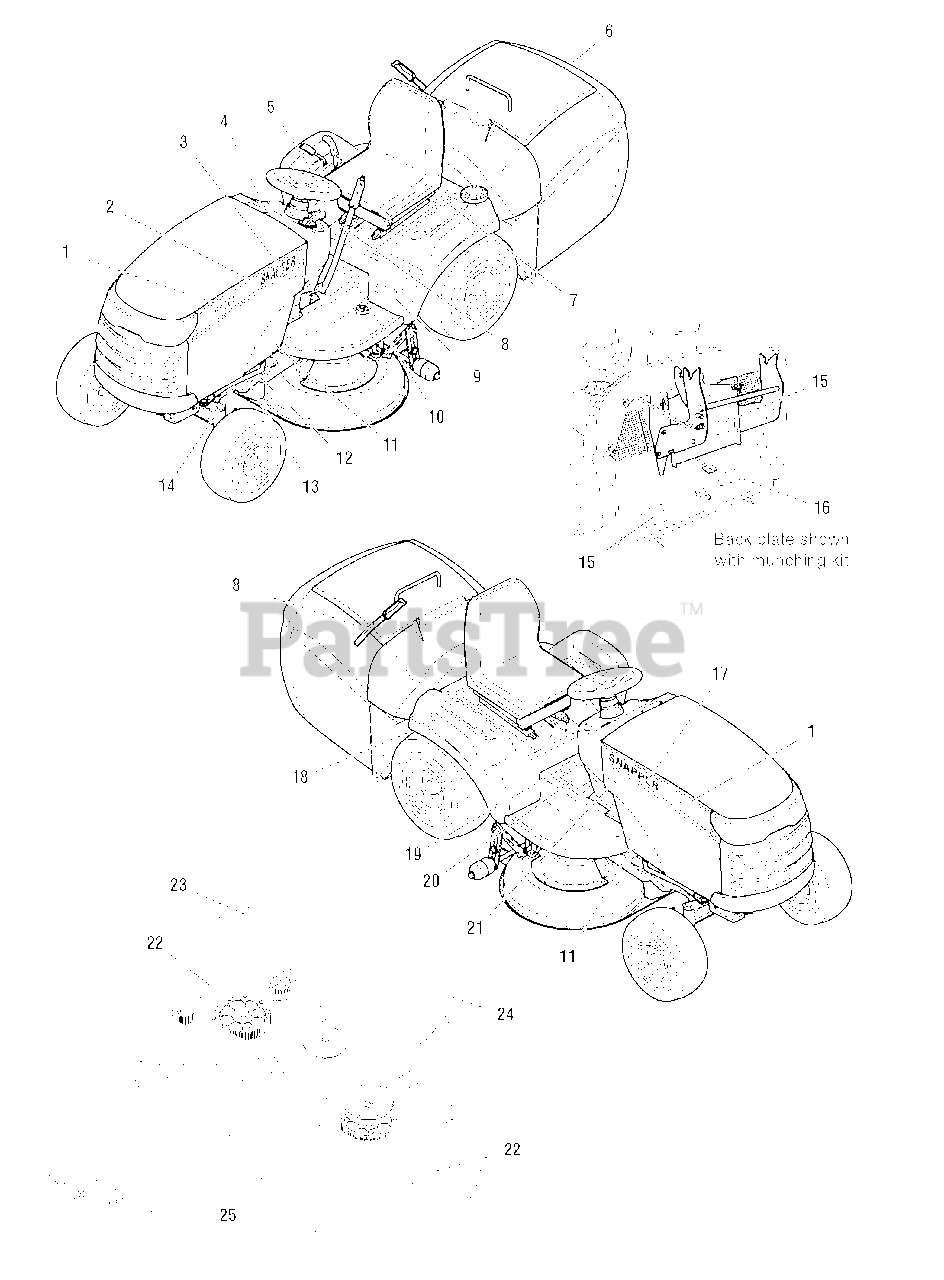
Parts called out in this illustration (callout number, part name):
1	DECAL, RD1740
1	DECAL, RD1840
1	DECAL, RD2040
2	DECAL, Hood Stripe, Snapper, LH
3	DECAL, Belt & Blade
4	DECAL, Ignition Switch
5	DECAL, Crusie / Lift
6	DECAL, Snapper
7	DECAL, Latch Release
8	DECAL, Hopper Lever
9	DECAL, Latch Release
10	DECAL, Hopper Pedal
11	DECAL, Protective, Clear
12	* DECAL, Patent
13	* DECAL, Serial Number, Tractor, (Not Serviced)
14	* DECAL, Decible Power Mass, Export Only, (Not Serviced)
15	DECAL, Danger Operating W/O Catcher
16	DECAL, Drawbar Max Load
17	DECAL, Hood Stripe, Snapper, RH
18	DECAL, Transmission Release Valve
19	DECAL, Danger Catcher Open
20	DECAL, Warning/Danger Icons, Tunnel
21	DECAL, Touch Up Paint
22	DECAL, Danger Rotating Blades
22	DECAL, Danger Rotating Blade, Export Only
23	DECAL, Height Of Cut
24	DECAL, Danger, Discharge Tube
25	* DECAL, Serial Number, Mower Deck, (Not Serviced)
